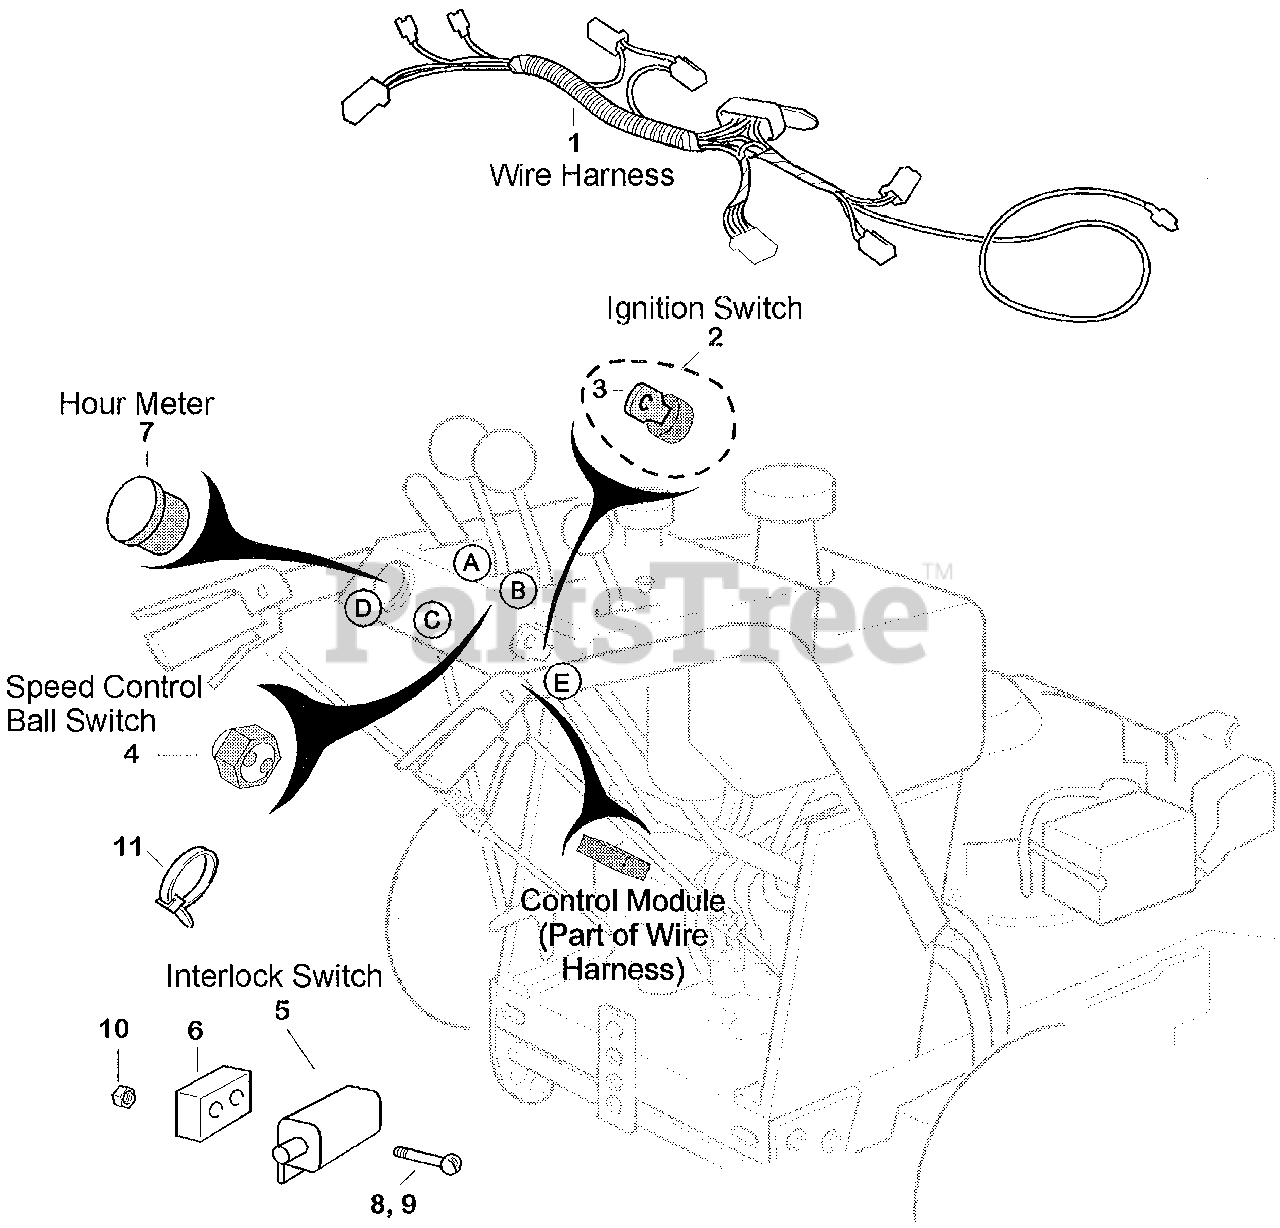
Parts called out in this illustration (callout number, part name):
1	WIRE HARNESS
2	SWITCH ASSY., COMBINATION
3	KEY, IGNITION
4	SWITCH, BALL
5	LIMIT, SWITCH
6	SPACER, SWITCH
7	METER ASSY., HOUR
